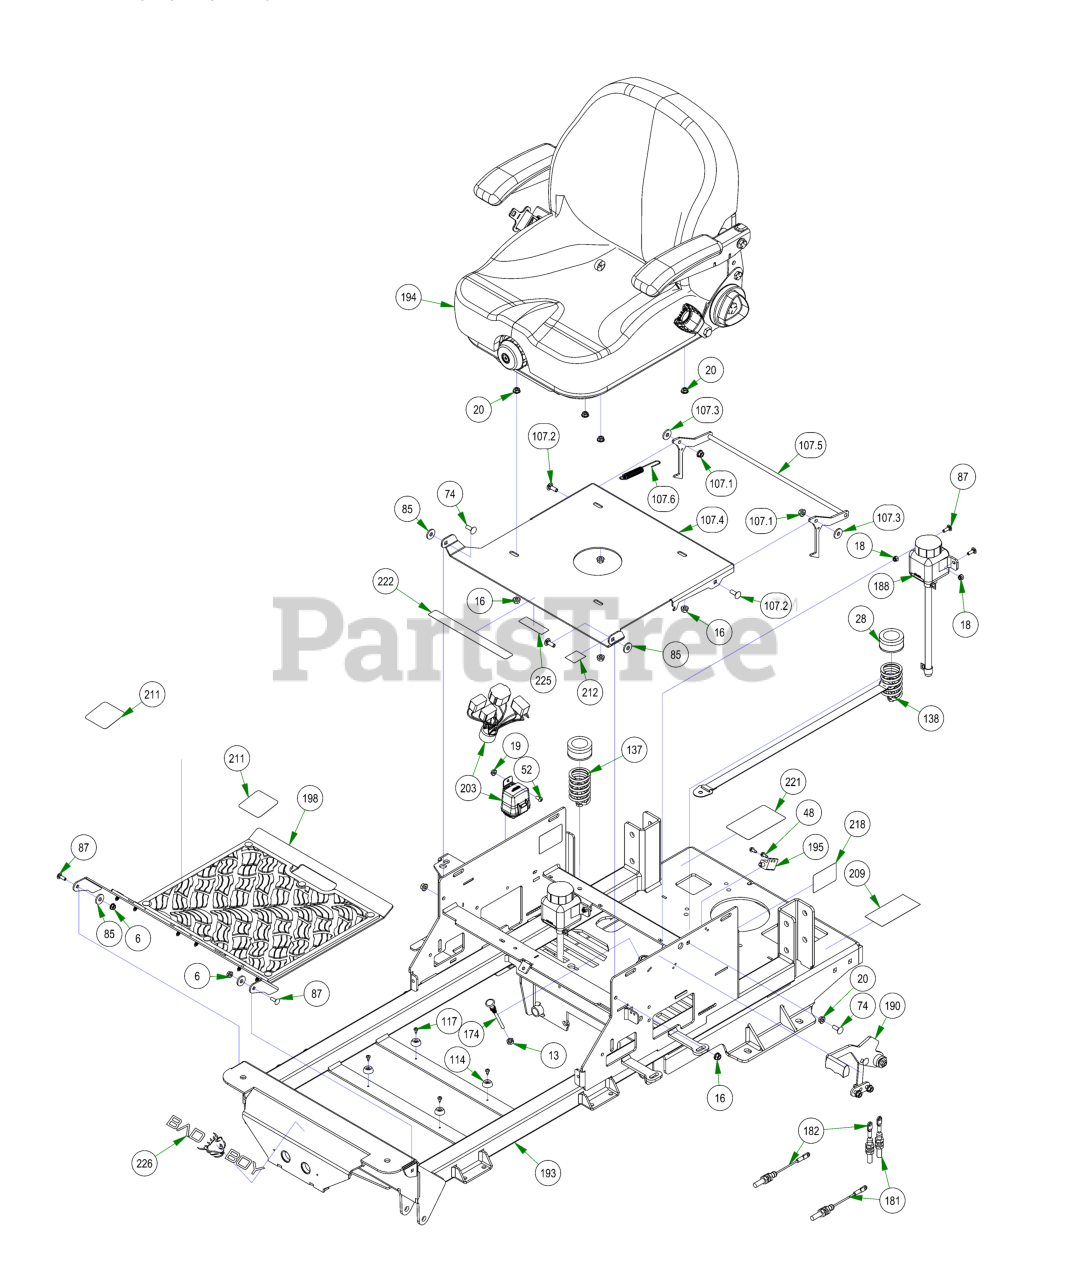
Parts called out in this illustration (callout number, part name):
6	1/4-20 NYL INSERT FLANGE LOCKNUT ZINC
13	3/8-24 HEX NUT ZINC YELLOW
16	5/16-18 NYLON INSERT FLANGE LOCKNUT ZINC
18	1/4-20 NYLON INSERT LOCKNUT ZINC
19	1/4-20 HEX SERRATED FLANGE NUT HARD/ZINC
20	5/16-18 HEX SERRATED FLANGE NUT HARD/ZINC
28	Seat Spring Cap Cover
48	12-24 X 1/2 HEX WASHER UNLSOT F TCS ZINC
52	1/4-20 X 1/2 BUTTON SOCKET CAP SCREW 18-8 STAINLESS STEEL
74	5/16-18 X 7/8 CARRIAGE BOLT ZINC
85	.360 ID X .983 OD X .120 THICK FLAT WASHER NYLON
87	1/4-20 X 3/4 CARRIAGE BOLT (GR.5) ZINC
106	2022 Maverick Rear Cover Assembly
107	MAVERICK/COMPACT OUTLAW SEAT PLATE ASSEMBLY
107.1	5/16-18 NYLON INSERT FLANGE LOCKNUT ZINC
107.2	5/16-18 X 7/8 CARRIAGE BOLT ZINC
107.3	.360 ID X .983 OD X .120 THICK FLAT WASHER NYLON
107.4	Seat Plate 2016
107.5	Seat Latch Rod Assembly
107.6	Brake Spring
114	Button Bumper
117	10-16 X 1/2 PAN PHIL TEK/3 CLIMASEAL OR ACF-SILVER COATED
137	Seat Spring Assembly
138	Seat Spring Assembly
181	2021 Load Balanced Brake Cable 1
182	2021 Load Balanced Brake Cable 2
188	Hydro Tank Assembly
190	2021 Load Balanced Brake Handle Assembly
193	2022 Maverick Frame - Painted
194	2022 Suspension Seat w/Seatbelt
195	Safety Switch
198	2021 Maverick Floorboard Assembly
203	Wiring Harness
209	2022 EPA Build Date Punch Label
211	2018 Maverick/2021 ZT Anti-Skid Steering Control Decals
212	2018 MZ/Magnum/ZT/MAV/Comp Out Brake Decal
218	Hydraulic Decal
221	Maverick Pump Belt Decal
222	Outlaw Warning Decal
225	Not For Sale In California
226	Flying Bulldog Front Bumper Decal
